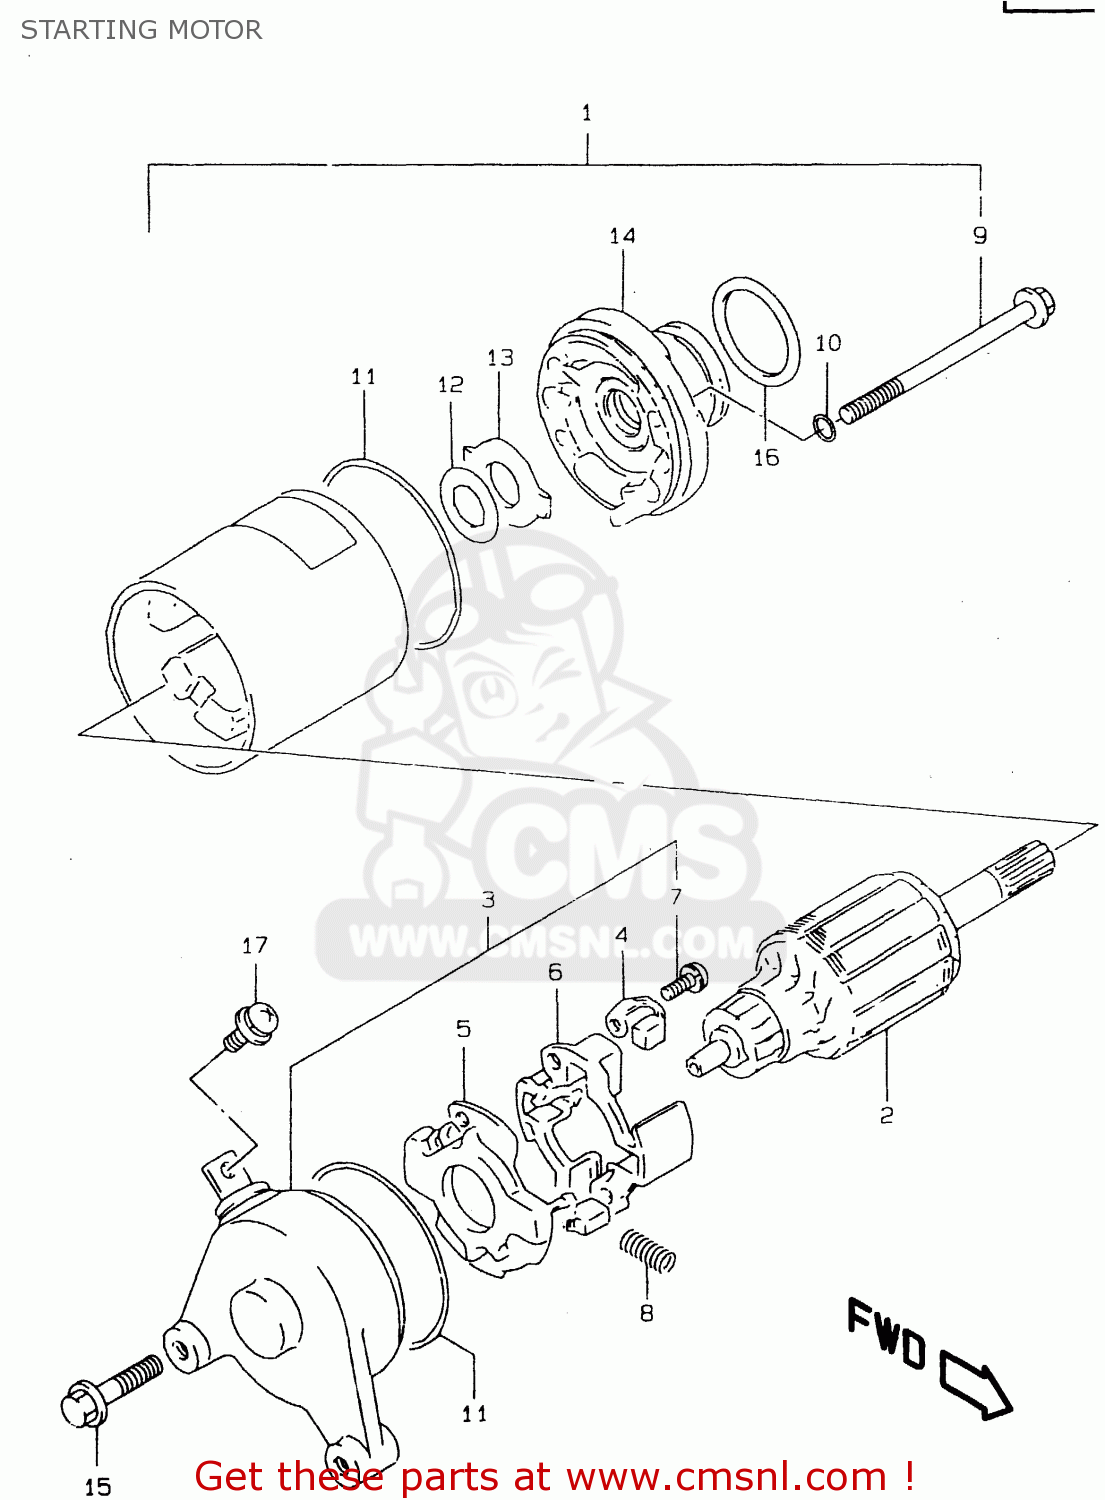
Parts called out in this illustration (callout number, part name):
1	MOTOR ASSY,STARTING
2	ARMATURE
3	FRAME ASSEMBLY,COMMUTATOR
4	BRUSH
5	BRUSH SUB ASSY,STARTER
6	HOLDER,BRUSH
7	SCREW
8	SPRING
9	BOLT
10	O RING
11	O RING
12	SHIM
13	PLATE,LOCK
14	BRACKET
15	BOLT
16	O RING(D:3,ID:24.5)
17	SCREW(5X8)
